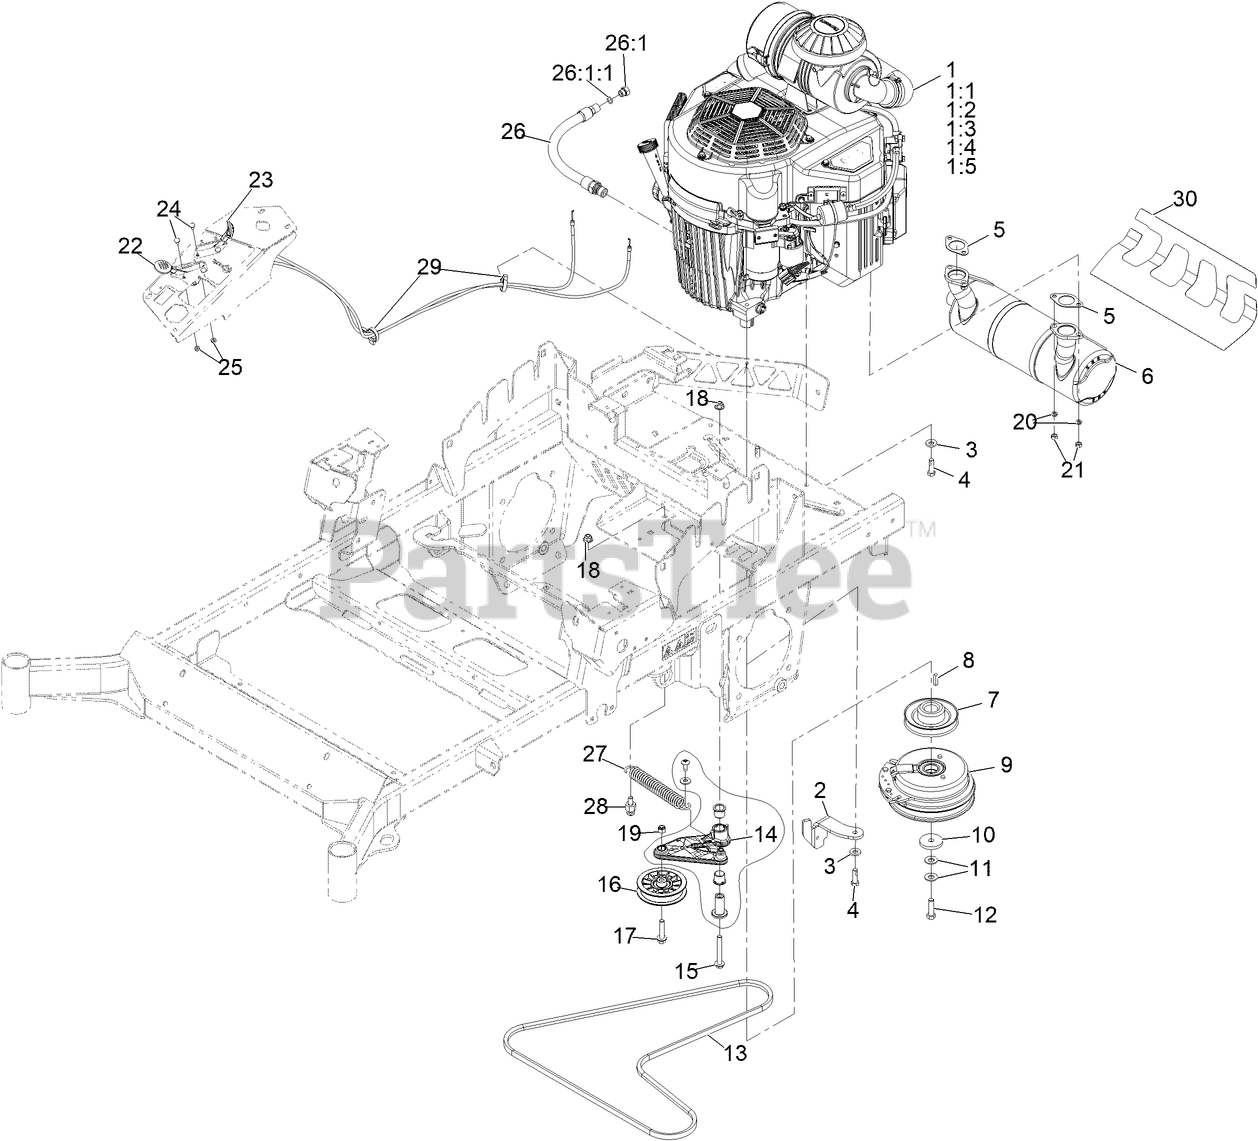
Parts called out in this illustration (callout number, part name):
1:1	FILTER-OIL KAW
1:2	ELEMENT-FILTER, AIR (OUTE
1:3	ELEMENT-FILTER, AIR (INNE
1:4	FILTER-FUEL
1:5	Spark Plug
2	Bracket, Clutch Anchor
3	WASHER-BELLEVILLE
4	Screw-HH, Patch
5	GASKET, EXHAUST
6	MUFFLER, KAWASAKI
7	Sheave, Engine
10	WASHER-CLUTCH
11	WASHER-SPRING
12	SCREW-HH 7/16-20 X 1 1/2 W/LOCTITE
13	Belt, A-Section
14	ASM, Idler Arm W/ Bushings
15	SCREW-HFH
16	PULLEY-FLAT IDLER
17	SCREW-HHF
18	NUT-HF, NI
19	NUT-LOCK, NI
20	WASHER-LOCK
22	CABLE-CONTROL, THROTTLE
23	ASM, CHOKE CABLE
24	BOLT-CARR
25	NUT-LOCK, NI
26	ENGINE OIL DRAIN HOSE ASM
26:1	PLUG-HH
26:1:1	O-RING
27	Spring, Extension
28	PIN, SPRING ANCHOR
29	CLAMP-HOSE
30	Shield, Heat
